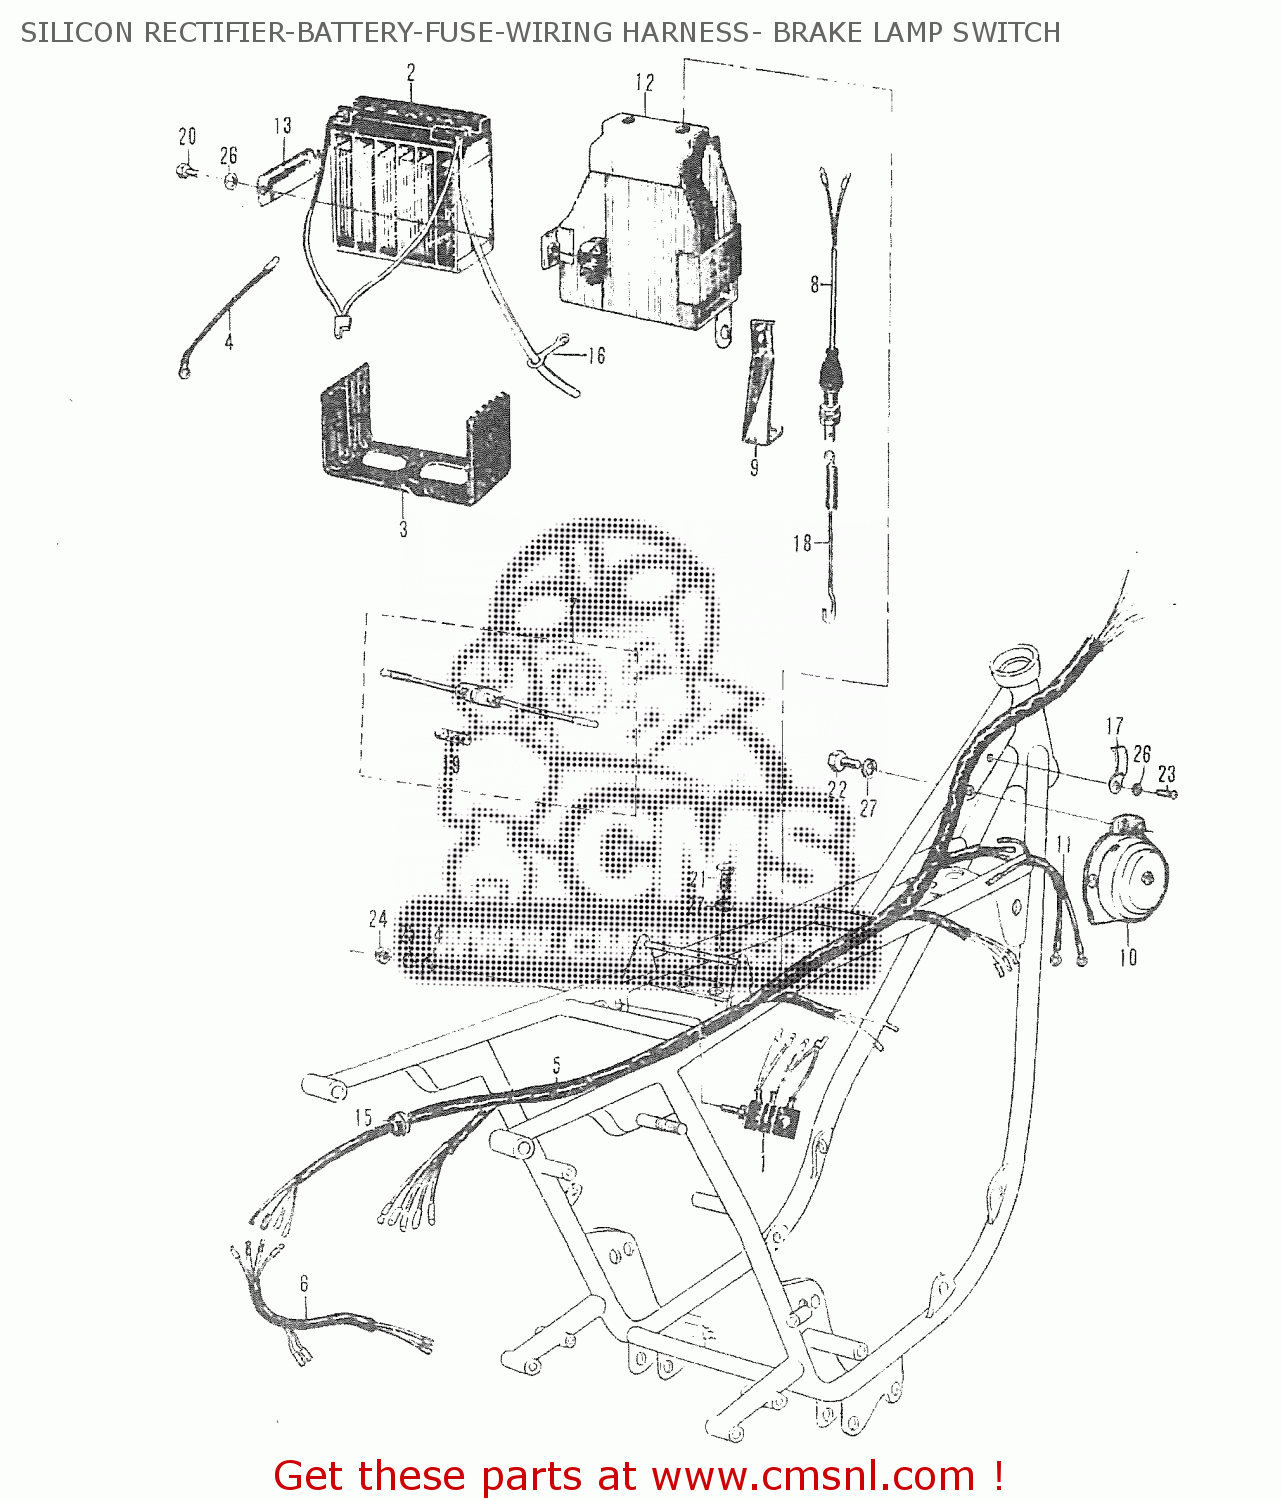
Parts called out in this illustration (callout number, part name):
1	RECTIFIER ASSEMBLY
2	BATTERY ASSEMBLY
3	CUSHION,BATTERY
4	BATTERY GROUND CABLE
5	MAIN WIRING HARNESS
6	TAIL/BRAKE LAMP WIRING HARNESS
7	BOX ASSEMBLY,FUSE
8	SWITCH ASSEMBLY,STOP LAMP
9	BRAKE LAMP SWITCH BRACKET
10	HORN ASSEMBLY
11	HORN WIRING HARNESS
12	BATTERY HOLDER
13	BATTERY HOLDER PLATE
14	WASHER
15	GROMMET
16	CLAMP
17	CLAMP
18	SPRING
19	FUSE(15A)
20	HEXAGON BOLT
21	SMALL HEAD HEXAGON BOLT
22	SMALL HEAD HEXAGON BOLT
23	CROSS HEAD SCREW
24	HEXAGON NUT
25	LOCK WASHER
26	LOCK WASHER
27	LOCK WASHER
